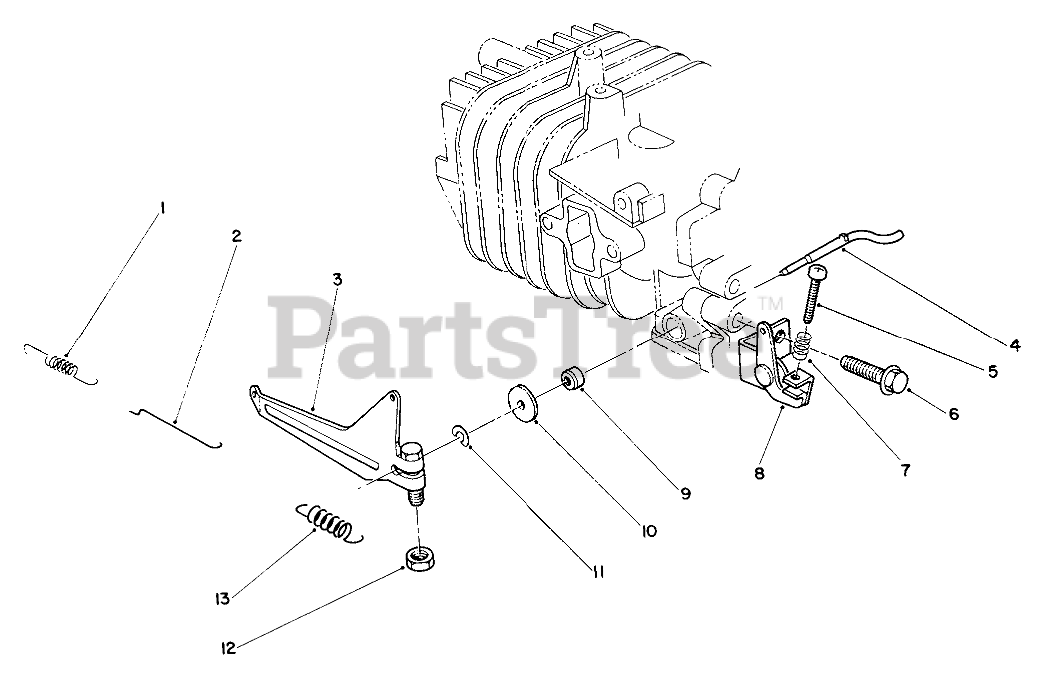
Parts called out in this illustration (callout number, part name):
1	CARB SPRING
2	CARB ROD
3	GOVERNOR ARM
4	SHAFT
5	SCREW
7	SPRING
8	GOV SPR BRKT
9	SEAL-OIL
10	WASHER
11	E-RING
13	GOV SPRING
